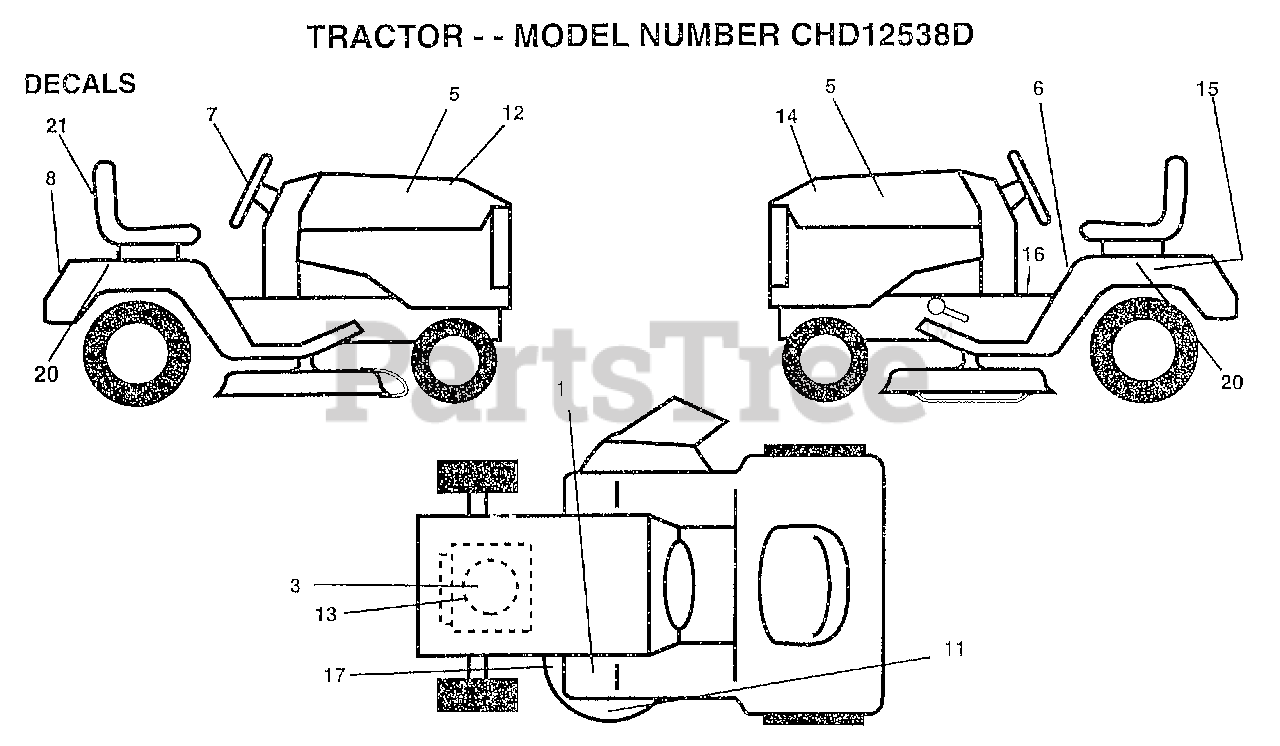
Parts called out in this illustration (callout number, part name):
1	DECAL T
3	DECAL ENGINE
5	"DECAL,DASH PNL"
6	DECAL.CAUT.ENG/FR
7	DECAL, INS STRG WH
8	DECAL.FENDER.LOGO
11	DECAL.MOWER.HOME
12	DECAL HOOD RH
13	DECAL.ENGINE.REPL
14	DECAL HOOD LH
15	DECAL.BATRY.3-3908
16	"DECAL.OPER,SDL"
17	DECAL
20	DECAL.FEND.SD.5SP
21	DECAL.SEAT REPLACEMENT
